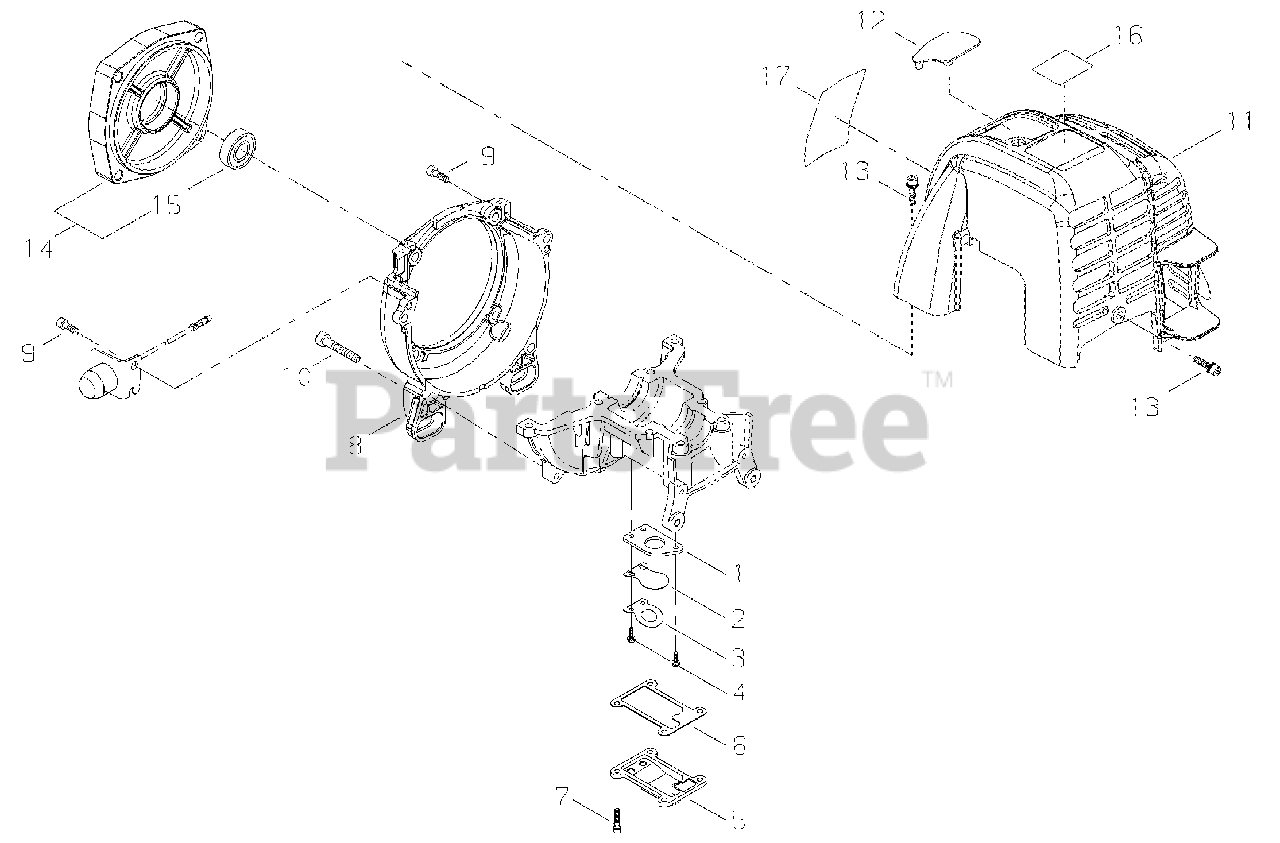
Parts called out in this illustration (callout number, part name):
1	PLATE, REED BACKING
2	VALVE, REED
3	STOP, REED VALVE
4	SCREW - 3X10
5	COVER, REED VALVE
6	GASKET, REED VALVE
7	SCREW - 4X14
8	CASE, FAN
9	SCREW - 5X16
10	SCREW - 5X30
11	COVER, ENGINE
12	COVER, SPARK PLUG
13	SCREW - 4X14
14	ADAPTER SET
15	BEARING, BALL - 6002
16	LABEL - MODEL GP3410
17	LABEL - C4
